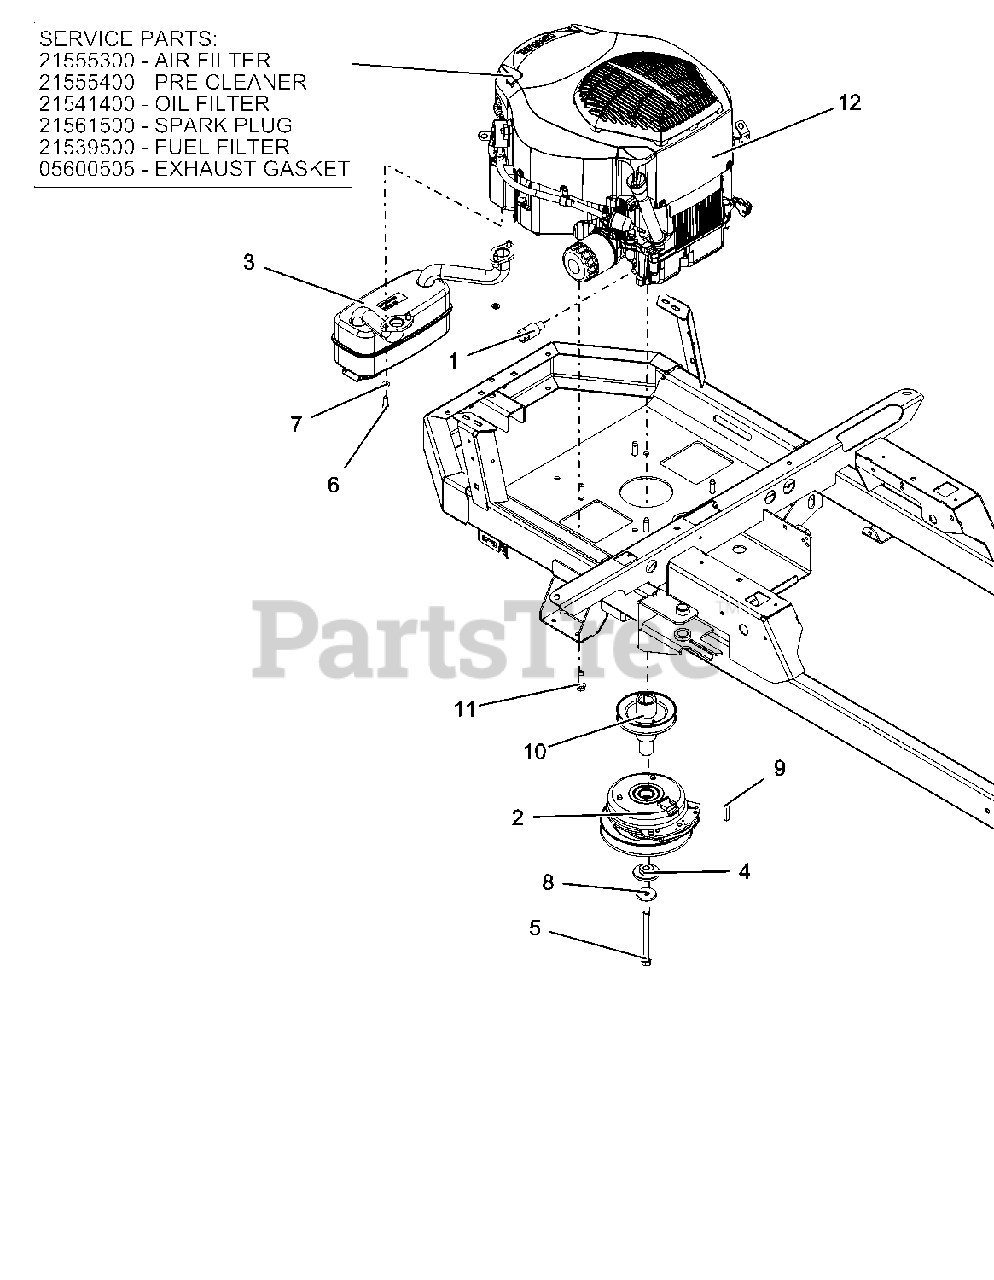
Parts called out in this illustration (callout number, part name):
1	DRAIN, OIL
2	CLUTCH, ELEC 105 FT LB MONOPOLE 6.83"
3	MUFFLER, KOHLER
4	BSHG, -FLG .469 x 1.06 x .574 x 2.0
5	BLT-HEX .44-20X4.50 GR8 YWZC NYTORQ
6	SCR, CAP SOCKET HEAD
7	WSHR-LK .31X.078 REG YWZC
8	WSHR, 7/16" SPRING DISC
9	KEY-SQ .250X.250X1.250
10	WLDMT, DRIVE SHEAVE X (2016)
11	SCR-TAP .38-16X1.25 HWH TR YZ
12	ENGINE, KOHLER PRO25 W/SC
12	AIR FILTER
12	PRE CLEANER
12	OIL FILTER
12	SPARK PLUG
12	FUEL FILTER
12	EXHAUST GASKET
